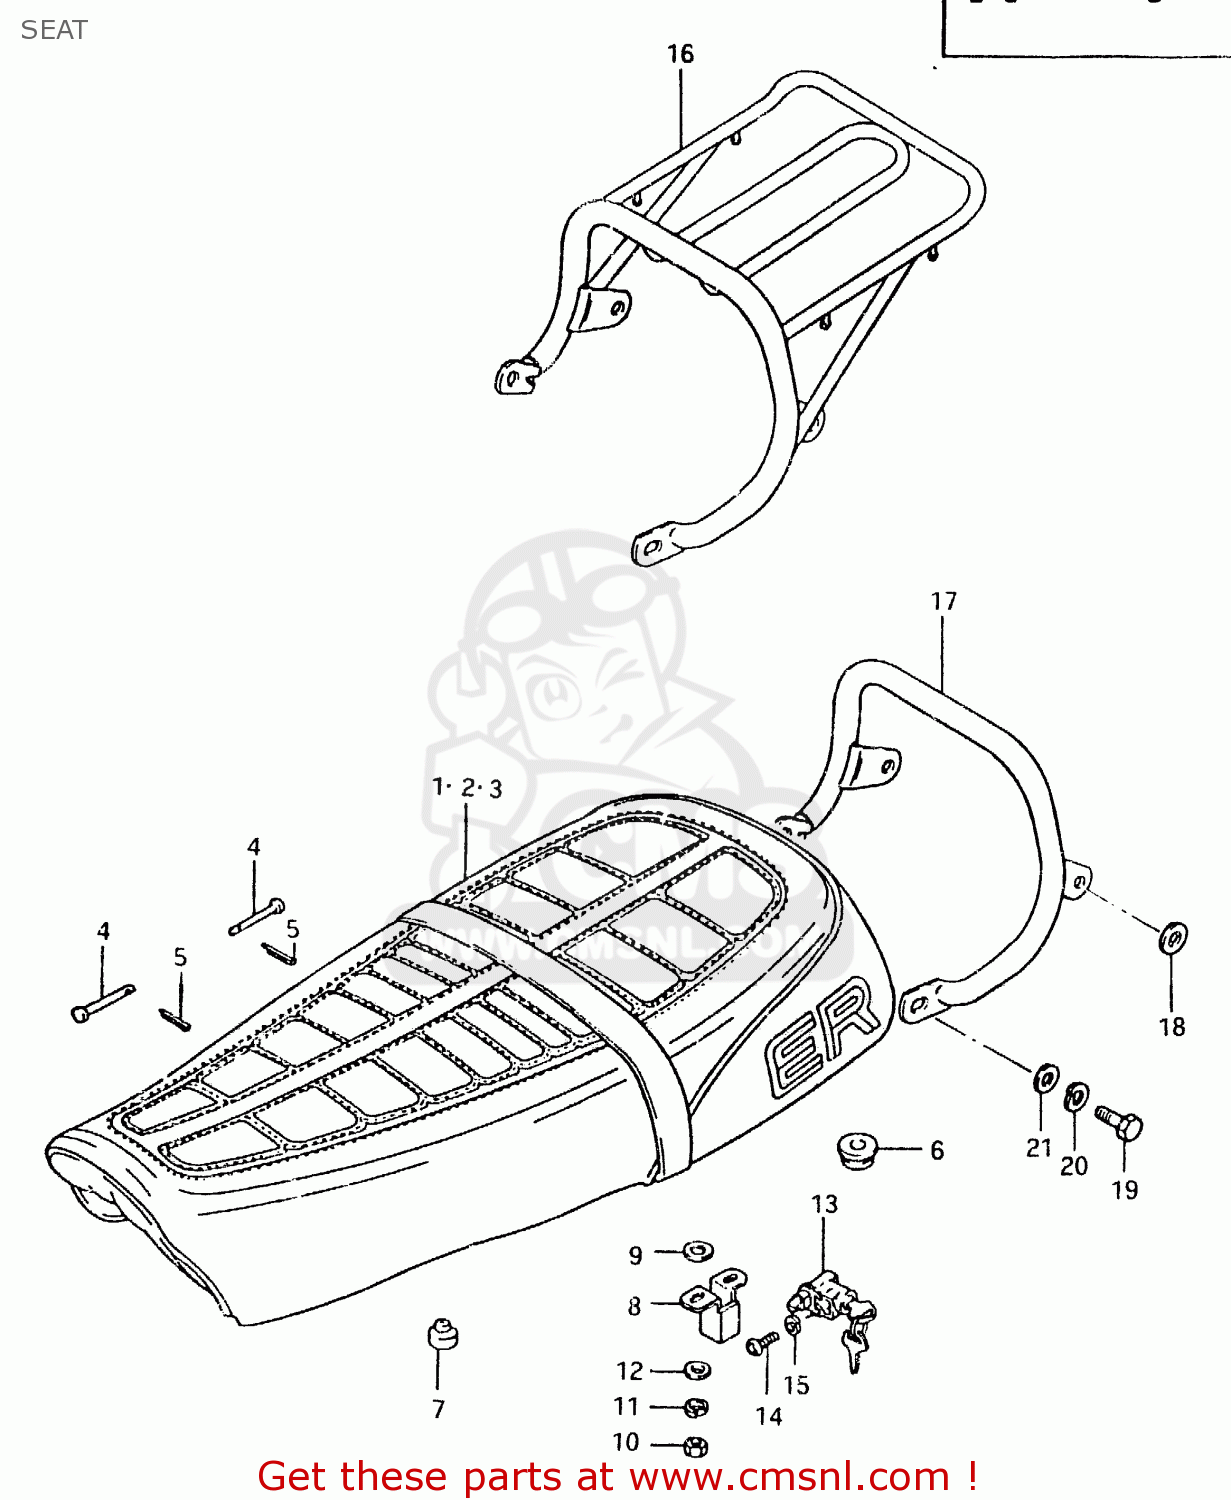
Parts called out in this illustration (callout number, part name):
1	SEAT ASSY (BLACK)
2	SEAT ASSY (BLACK)
3	SEAT ASSY (BLACK)
4	PIN
5	PIN
6	CUSHION
7	CUSHION
8	PLATE,CLAMP GUIDE
9	WASHER(8.5X18X1)
10	NUT
11	LOCK WASHER
12	WASHER
13	LOCK ASSY,SEAT
14	SCREW
15	LOCK WASHER
16	CARRIER,SPORT
17	HANDLE, PILLION RIDER
18	WASHER
19	BOLT
20	LOCK WASHER
21	WASHER
